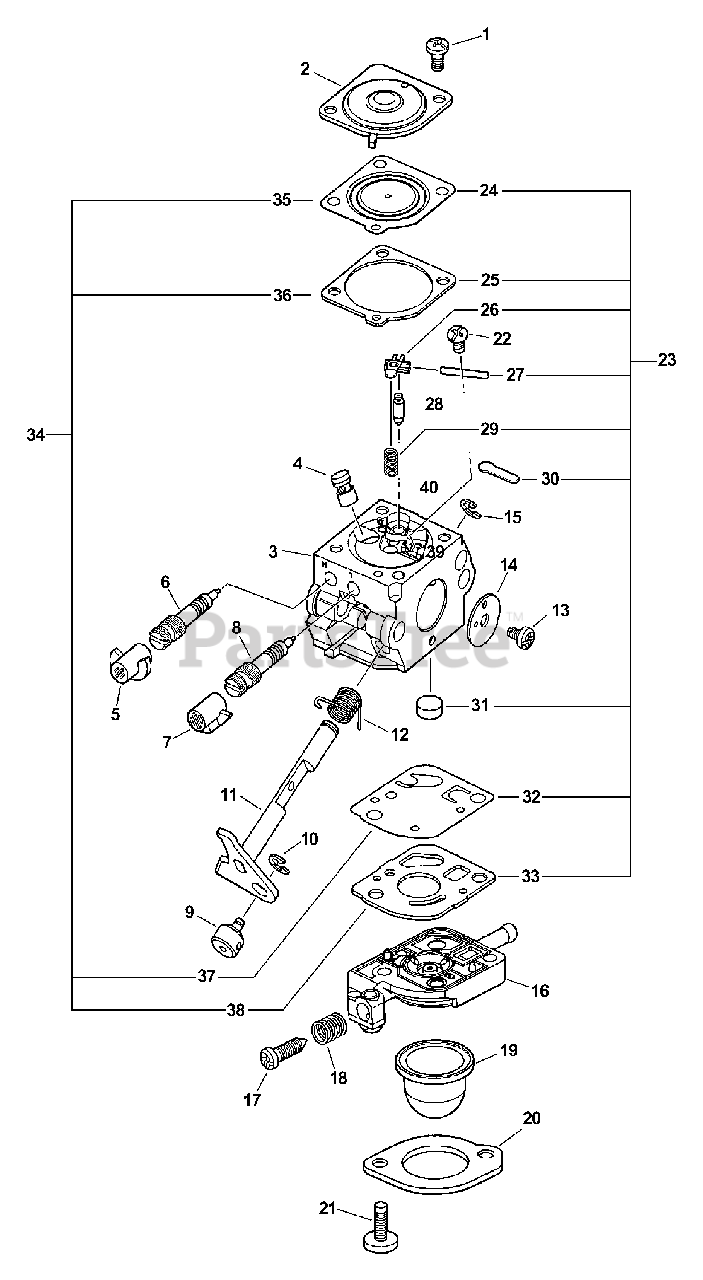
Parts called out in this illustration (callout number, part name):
2	COVER, METERING
3	BODY, CARBURETOR
4	NOZZLE, CHECK VALVE
5	CAP, LIMITER
6	NEEDLE - HIGH SPEED
7	CAP, LIMITER
8	NEEDLE - LOW SPEED
10	RING, RETAINING
11	SHAFT, THROTTLE
12	SPRING, RETURN
14	VALVE, THROTTLE
15	RING, RETAINING
16	BASE, PURGE
17	SCREW, IDLE ADJUST
18	SCREW, IDLE ADJUST
19	BULB, PURGE
20	RETAINER, PURGE BULB
21	SCREW, RETAINER
22	SCREW, METERING LEVER PIN
23	REPAIR KIT
24	DIAPHRAGM, METERING
25	GASKET, METERING
26	LEVER, METERING
27	PIN, METERING LEVER
28	VALVE, INLET NEEDLE
29	SPRING, METERING LEVER
30	PLUG, WELCH
31	STRAINER
32	DIAPHRAGM, PUMP
33	GASKET, PUMP
34	DIAPHRAGM/GASKET KIT
35	DIAPHRAGM, METERING
36	GASKET, METERING
37	DIAPHRAGM, PUMP
38	GASKET, PUMP
